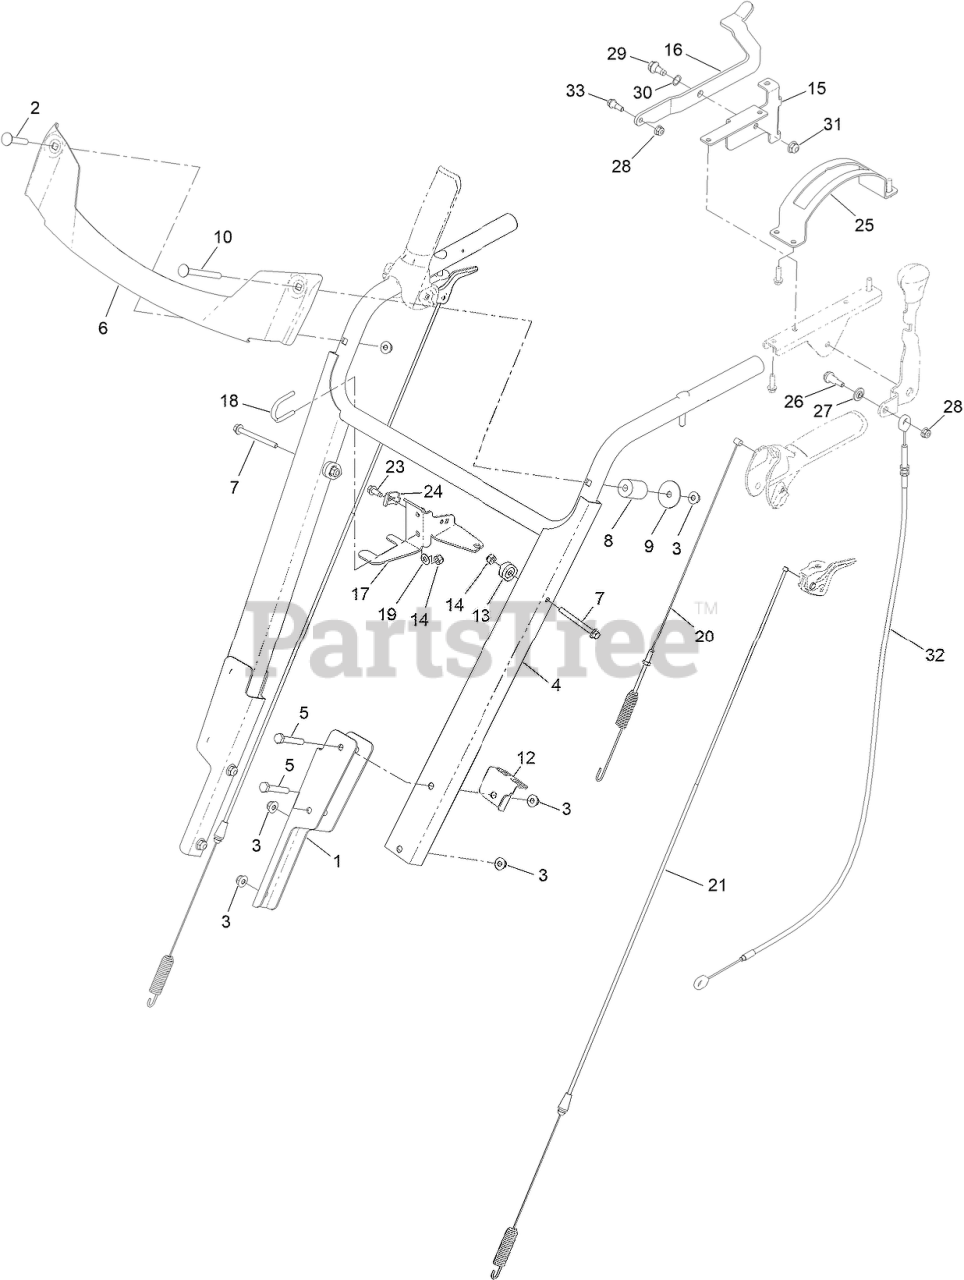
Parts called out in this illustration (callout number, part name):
1	BRACKET-HANDLE, LOWER
2	BOLT-CARR
3	NUT-HF
4	HD HANDLE ASM
5	SCREW-HH
6	TRIM-METAL, HD
7	SCREW-HHF
8	SPACER
9	WASHER-FLAT
10	SCREW-CARR
12	BRACKET-STICK, CLEANOUT
13	CLAMP-CABLE
14	NUT-HEX
15	BRACKET-LEVER
16	LEVER-ADJUSTMENT, TRACK
17	BRACKET-CABLE, SPEED
18	CLAMP-LIGHT
19	WASHER-FLAT
20	CABLE - TRACTION UPPER
21	CABLE-CLUTCH
23	SCREW-HWH
24	CLAMP-CABLE
25	GATE-SHIFT, SPEED
26	BOLT-SHOULDER
27	WASHER-STEPPED
28	NUT-FLANGE, NI
29	SCREW-SHOULDER
30	WASHER, WAVE
31	NUT-HF
32	CABLE-HYDRO, PUSH PULL
33	BOLT-SHOULDER
